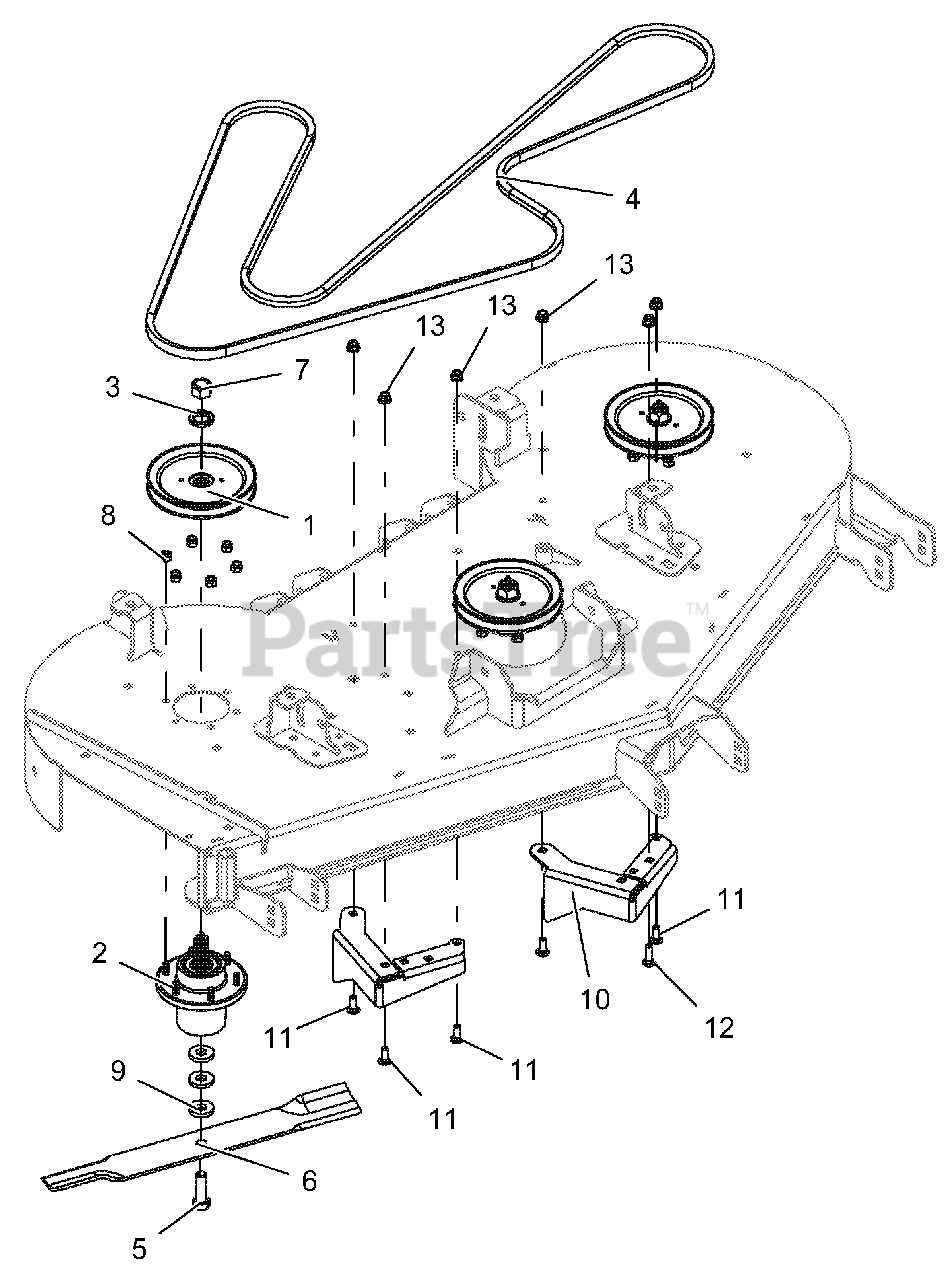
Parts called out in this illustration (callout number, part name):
1	PULLEY, SPINDLE 6.75 OD .76 HB - BLACK
2	ASSY, SPINDLE HOUSING
3	SPCR, 1.005 x 1.505 x .250 PM
4	V-Belt, 5L-WRAPPED CLUTCHING
5	BLT-HEX .62-11 x 2.00 GR8 YWZC
6	BLADE, 21.000 x .80 LIFT
7	LOCKNUT, 3/4-16 CROWN GR5 Y
8	NUT-LK-NYL .38-16 YWZC
9	WSHR-FL-STL .630 x 1.50 x .25 YWZC
10	DEFLECTOR, DIRECTION
11	BLT-RDHDSQNK .38-16 x 1.00 G5 YWZC
12	BLT-RDHDSQNK .38-16 x 1.25 G5 YWZC
13	NUT-LK-NYL-FLG .38-16 YWZC
